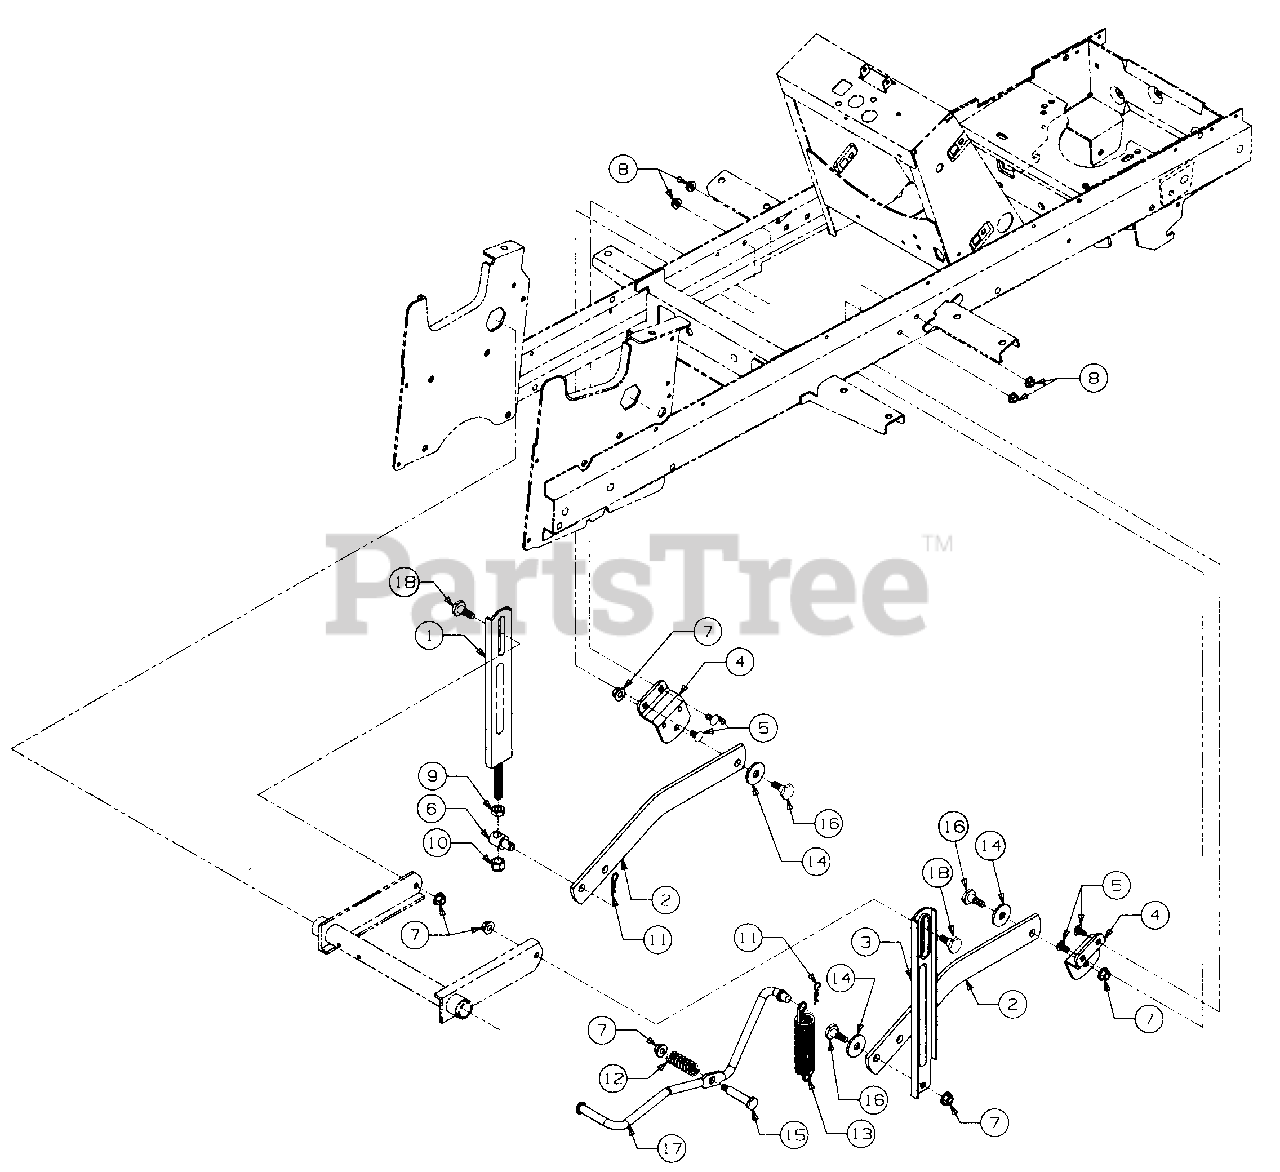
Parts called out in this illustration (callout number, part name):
2	Link, Lift
5	Bolt, Carriage, 5/16-18 x .62 Lg
6	Ferrule, Adjustment
7	Nut, Hex Flanged Lock, 3/8-16
8	Nut, Hex Flange Top Lock 5/16-18
9	Nut, Hex Jam, 1/2-13 GR5
10	Nut, Hex Top Nylon Lock, 1/2-13
11	Pin, Internal Cotter, .092 Dia x 1.63 Lg
12	Spring, Compression, .63 ID x 2.0 Lg
13	Spring, Extension, 1.0 OD x 6.42 Coils, Light Duty 46" Dock
14	Washer, Flat, .50 x 1.5 x .1 5 Thk
15	Bolt, Shoulder
16	Bolt, Shoulder
17	Rod, RH Lift Assist
18	Bolt, Shoulder
